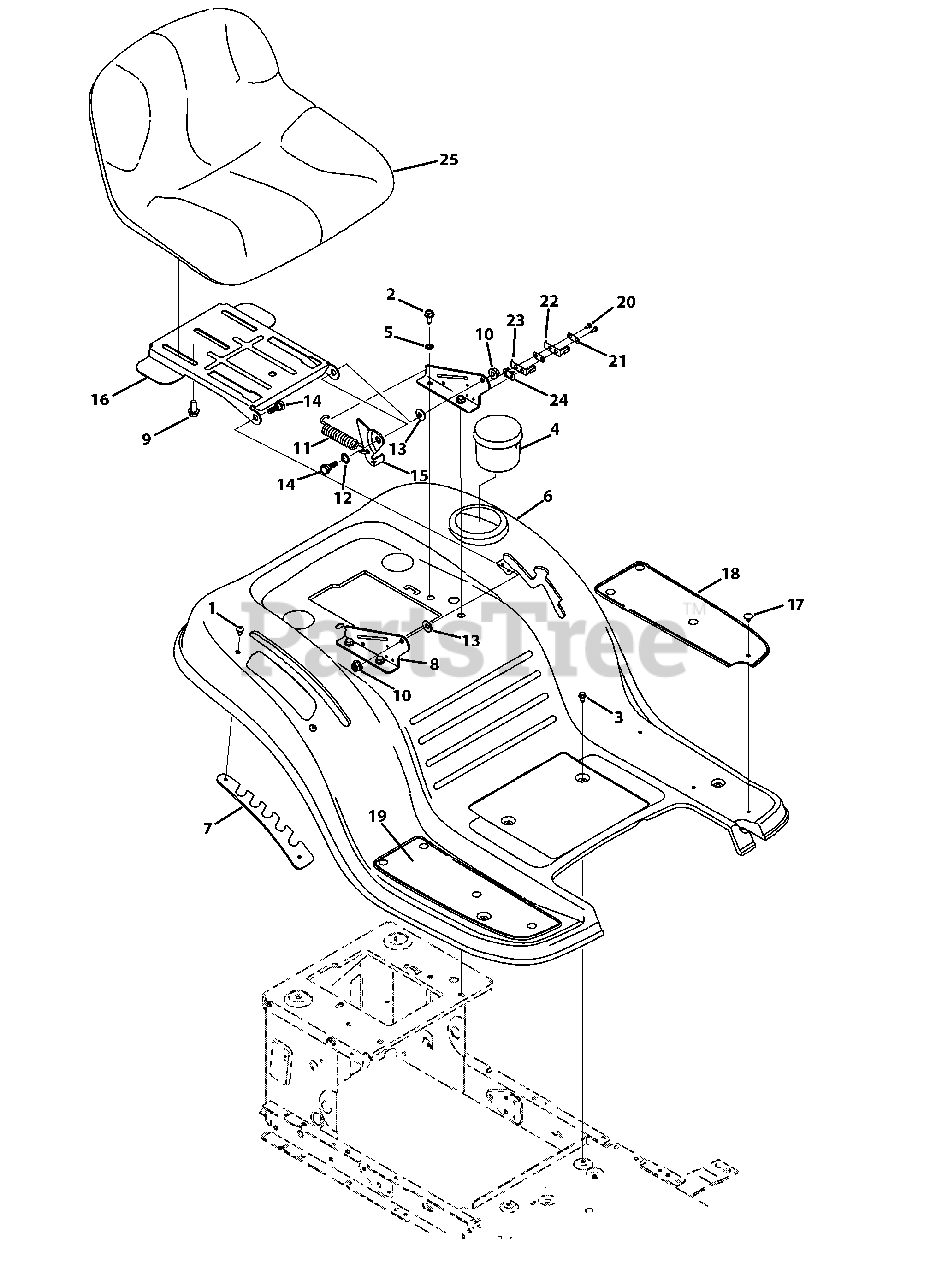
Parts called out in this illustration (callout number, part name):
1	Screw, 1/4-20 x .500
2	Screw, 5/16-18 x .750
3	Screw Pan Torx Head, 1/4-20 x .500
4	Cup Holder
5	Loack Washer, 5/16
6	Fender - Red
7	Lift Adjuster Bracket
8	Seat Mount Bracket
9	Hex Flange, 3/8-16 x .875
10	Flangelock Nut, 5/16-18
11	Extension Spring
12	Flat Washer, .510x .750 x .033
13	Bell Washer, .340 x .872 x .060
14	Shoulder Screw, 5/16-18 x .437 x .268
15	Lift Seat Bracket
16	Pivot Seat Manual Adjust Bracket
17	Ratchet Clip, .250 x .500
18	Foot Pad, LH
19	Foot Pad, RH
20	Screw, 8-18 x .500
21	Insulator Plate
22	Outer Seat SPring
23	Inner Seat Spring
24	Insulator Boss Plate
25	Medium Back Seat
